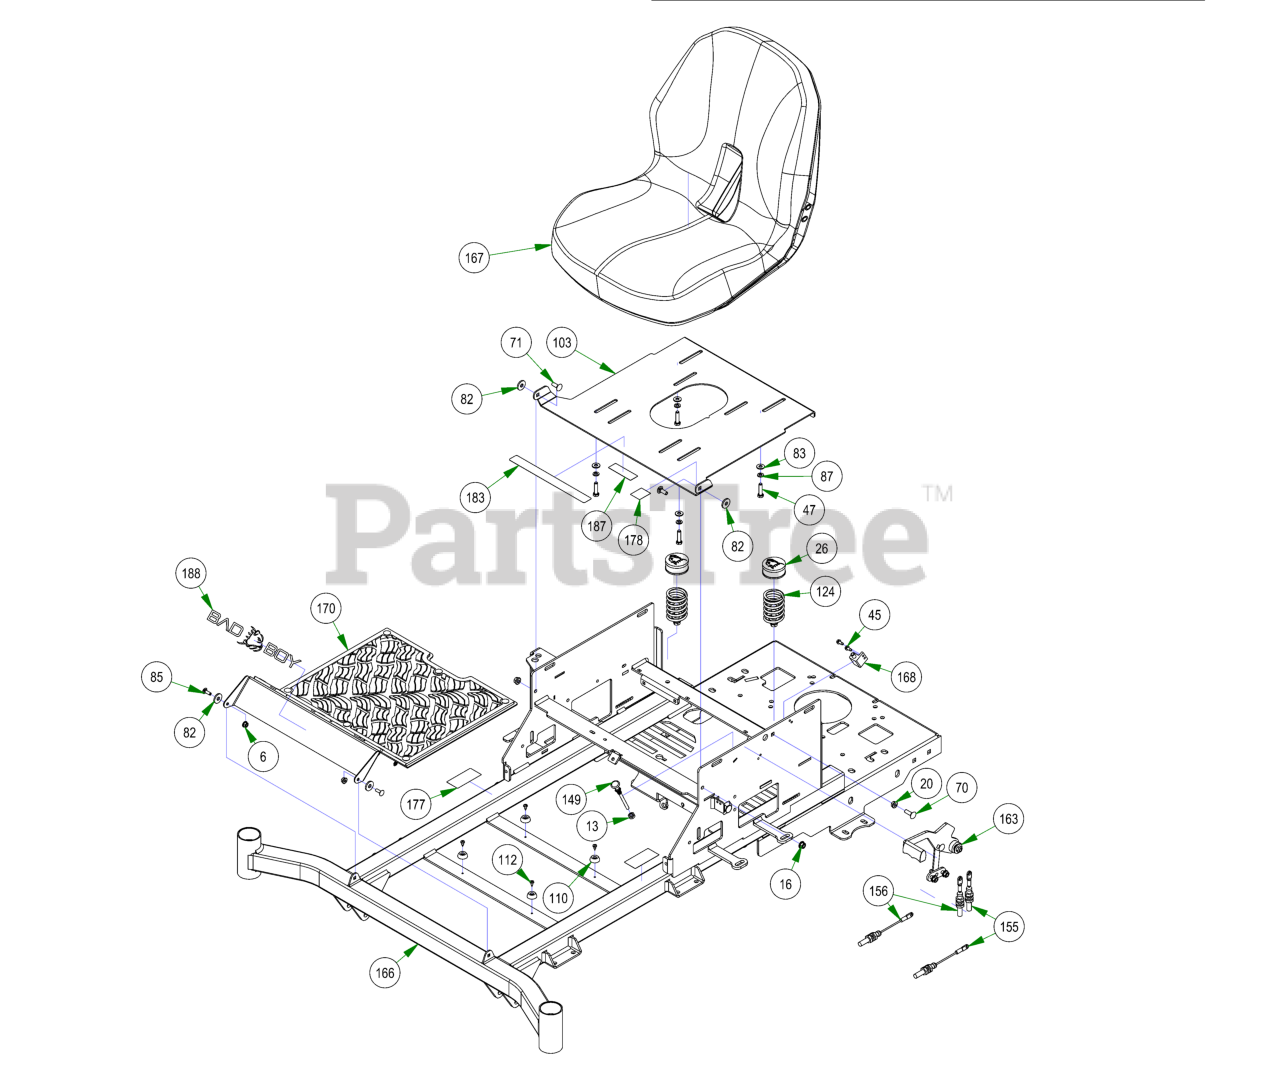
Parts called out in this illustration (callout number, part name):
6	1/4-20 NYL INSERT FLANGE LOCKNUT ZINC
13	3/8-24 HEX NUT ZINC YELLOW
16	5/16-18 NYLON INSERT FLANGE LOCKNUT ZINC
20	5/16-18 HEX SERRATED FLANGE NUT HARD/ZINC
26	Spring Cap Cover
45	12-24 X 1/2 HEX WASHER UNLSOT F TCS ZINC
47	5/16-18 X 1-1/4 HEX C/S (GR.5) ZC
70	5/16-18 X 1 CARRIAGE BOLT (GR.8) ZINC
71	5/16-18 X 7/8 CARRIAGE BOLT ZINC
82	.360 ID X .983 OD X .120 THICK FLAT WASHER NYLON
83	1/4 USS FLAT WASHER (3/4 OD) ZINC
85	1/4-20 X 3/4 CARRIAGE BOLT (GR.5) ZINC
87	5/16 SPLIT LOCKWASHER ZINC
103	2022 Avenger Seat Plate
110	Button Bumper
112	10-16 X 1/2 PAN PHIL TEK/3 CLIMASEAL OR ACF-SILVER COATED
124	Seat Spring Assembly
155	2021 Load Balanced Brake Cable 1
156	2021 Load Balanced Brake Cable 2
163	2021 Load Balanced Brake Handle Assembly
166	2022 MZ/ZT 54"-60" Frame
167	2022 Avenger Seat
167.1	Seat Switch
167.2	Avenger Seat Cover
167.3	Water Proofing Protection
168	Safety Switch
170	2020 MZ AVEN Floorboard Assembly
177	2018 LH/RH Steering Control Decal Roll
178	2018 MZ/Magnum/ZT/MAV/Comp Out Brake Decal
183	Outlaw Warning Decal
187	Not For Sale In California
188	Flying Bulldog Front Bumper Decal
